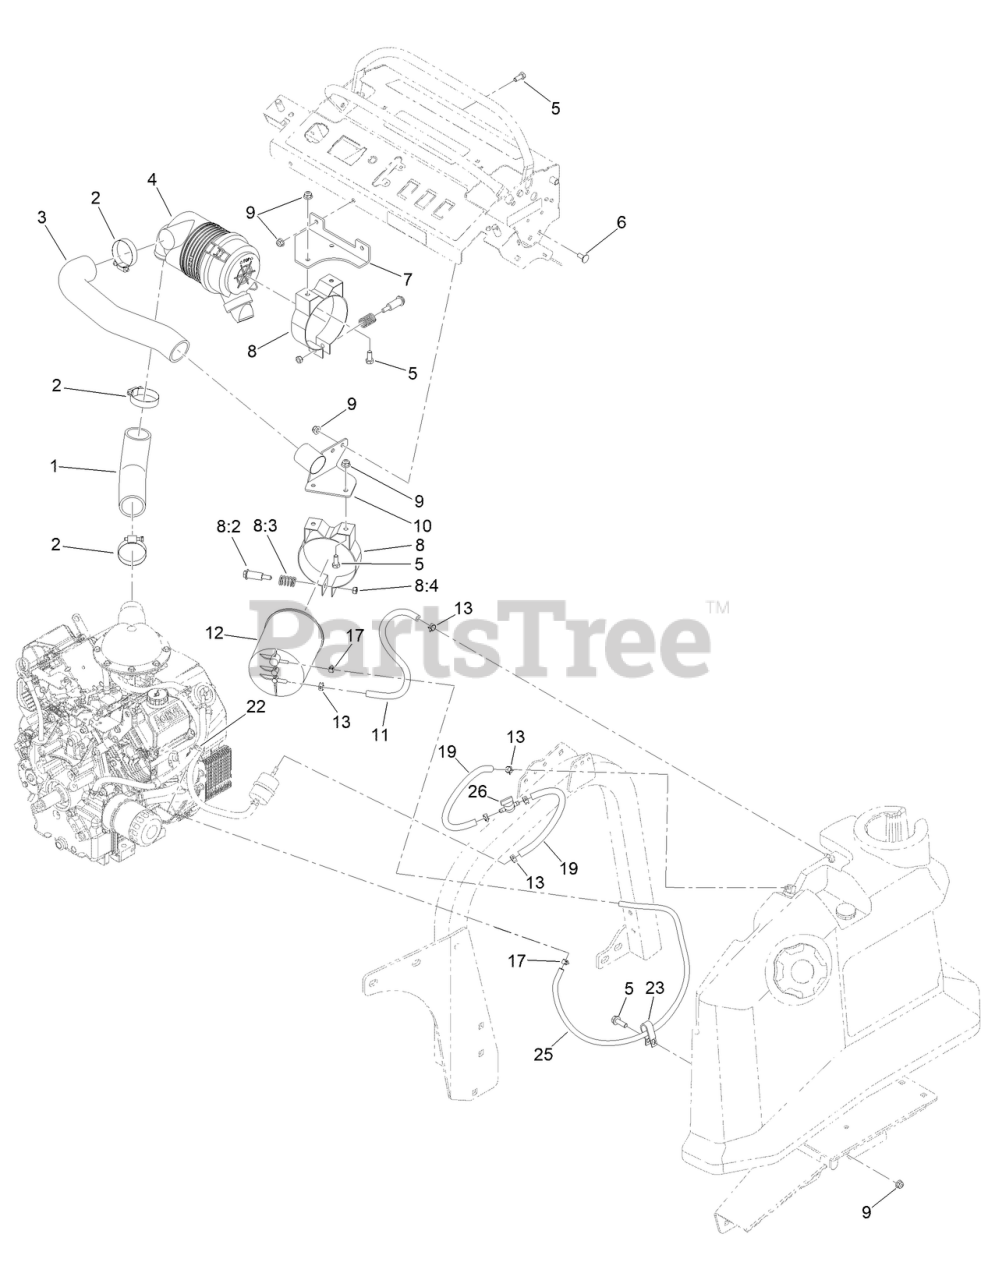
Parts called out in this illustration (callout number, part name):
1	HOSE-INTAKE, AIR
2	CLAMP-HOSE
3	HOSE-INLET ASM
4	AIR CLEANER ASM
5	SCREW-HH
6	SCREW-CARR
7	BRACKET-MOUNT, AIR-FILTER
8	AIR CLEANER MOUNTING BAND ASM
8:4	Nut-Lock, NI
9	NUT-HF, NI
10	CARB CANISTER MOUNT ASM
11	HOSE-FUEL
12	CANISTER-CARBON, 1200CC
13	CLAMP-HOSE
17	CLAMP-HOSE
19	HOSE-FUEL
22	TIE-CABLE
23	CLAMP-HOSE
25	Hose-Fuel
26	VALVE-FUEL
